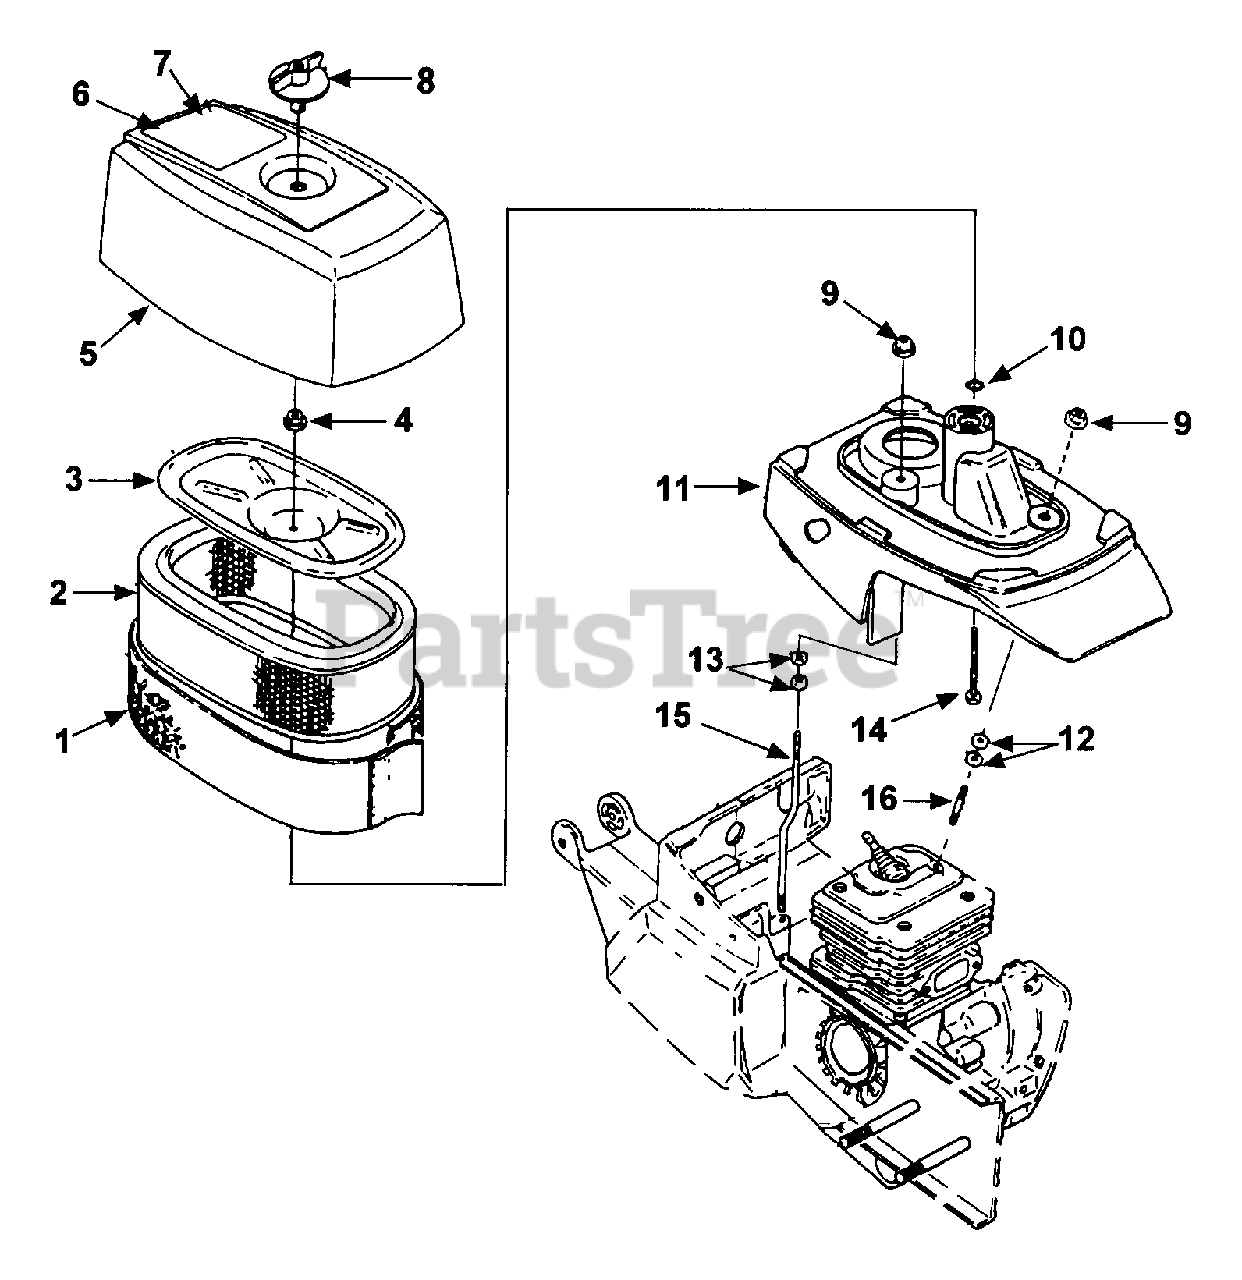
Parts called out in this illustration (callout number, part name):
1	PREFILTER - Felt
2	ELEMENT - Air Filter
3	COVER - Air Filter Element
4	NUT - Hex Conical
5	COVER - Air Filter
6	DECAL - Warning (French)
7	DECAL - Warning (Eng)
8	KNOB & INSERT
9	NUT - Hex
11	COVER - Cylinder
12	SPACER - Insulating
13	NUT - Hex
14	SCREW - Hex Cap (10-24 x 1 3/4")
15	STUD - Offset (10-24)
16	STUD (10-24 x 1")
